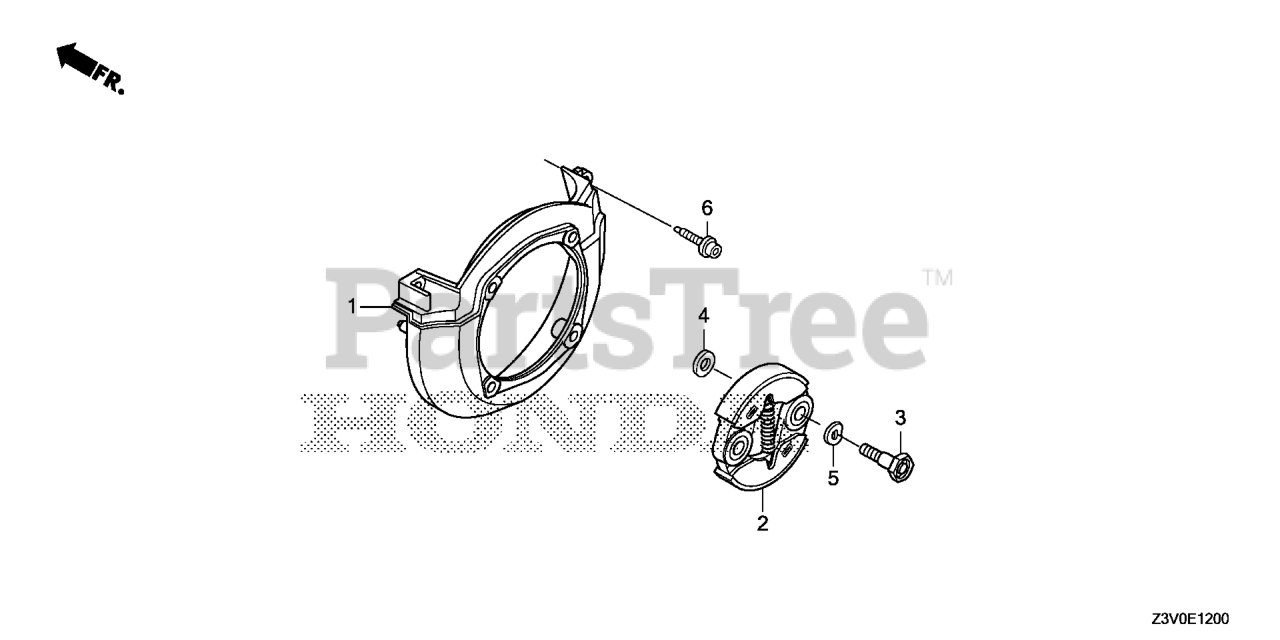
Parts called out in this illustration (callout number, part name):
1	COVER, FAN
2	CLUTCH ASSY.
3	BOLT, CLUTCH (8MM)
4	WASHER, CLUTCH (8X17)
5	WASHER, WAVE (10MM)
6	BOLT, SOCKET (5X20)
